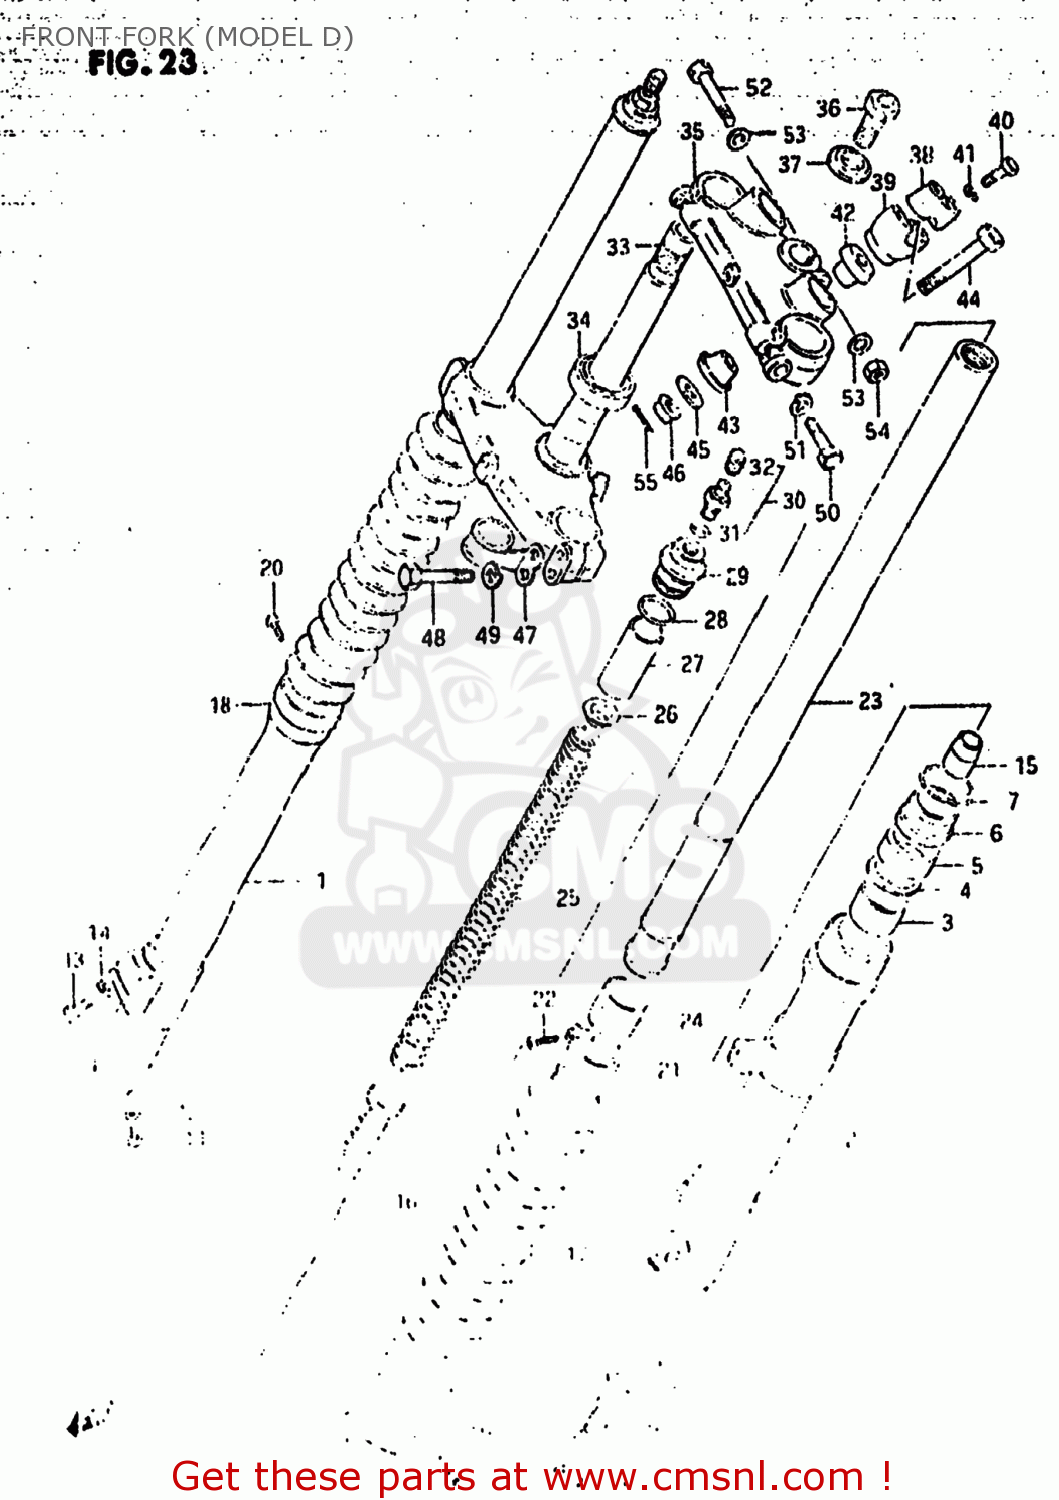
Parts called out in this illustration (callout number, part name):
1	TUBE,OUTER,RIGHT
2	TUBE,OUTER,LEFT
3	METAL,SLIDE
4	WASHER
5	SEAL,OIL
6	SEAL,DUST
7	RING,STOPPER
8	GASKET,FORK CYLINDER
9	VALVE,DF
10	CAP,FRONT FORK DF
11	SCREW 4X6
12	GASKET,DRAIN,PLUG (NAS)
13	BOLT (8X30)
14	WASHER,LOCK,8.
15	PIECE,FRONT FORK OIL LOCK
16	CYLINDER,FRONT FORK
17	BOOT,FRONT FORK COVER
18	BAND,BOOT,UPPER
19	BAND,FRONT FORK BOOT
20	SCREW
21	BAND,FRONT FORK BOOT
22	SCREW 4X10
23	TUBE,INNER
24	PISTON
25	SPRING,FRONT FORK
26	GUIDE,SPRING
27	SPACER,FRONT FORK SPRING
28	O RING
29	CAP,FORK INNER TUBE
30	VALVE,FRONT FORK AIR
31	O-RING
32	CAP,VALVE AIR
33	STEM,STEERING
34	BEARING
35	HEAD,STEERING STEM
36	BOLT
37	WASHER
38	HOLDER,HANDLE UPR
39	HOLDER,HANDLE LWR
40	BOLT
41	WASHER,LOCK,8.
42	DAMPER,UPR
43	DAMPER,LWR
44	BOLT,HANDLE HOLDER
45	WASHER,HANDLEBAR HOLDER
46	NUT
47	GUIDE,CABLE
48	BOLT 8X40
49	WASHER,LOCK,8.
50	BOLT
51	WASHER,LOCK,8.
52	BOLT 8X50
53	WASHER
54	NUT
55	PIN 20X20
